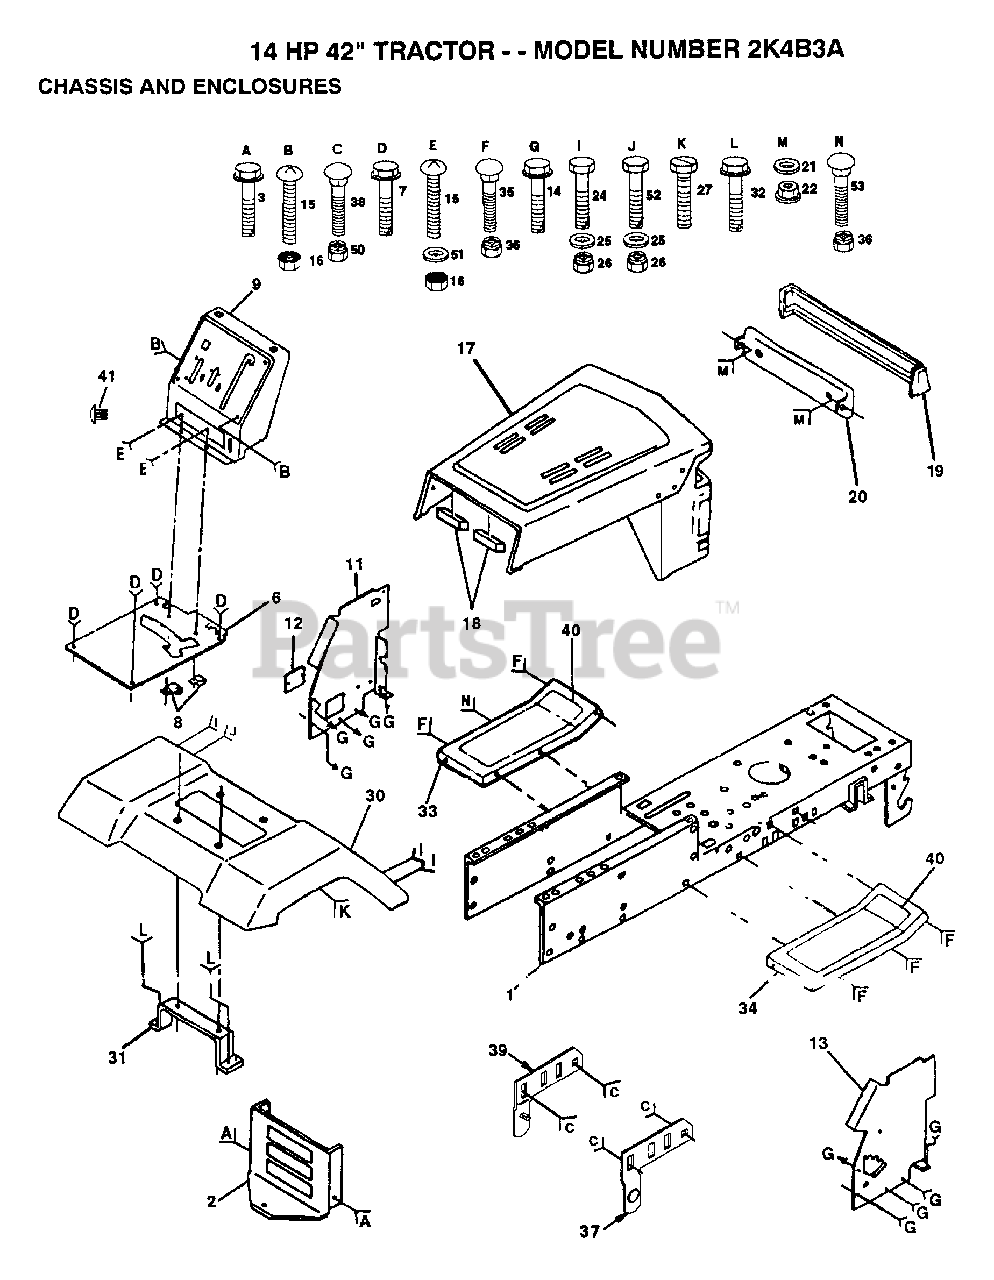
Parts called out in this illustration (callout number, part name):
3	SCREW
7	SCREW LT
8	CLIP T
11	PANEL DASH LH
12	COVER ACCESS
14	SCREW LT
15	SCREW
17	HOOD/GRILL ASM
21	WASHER PM
22	PAL NUT LT
25	WASHER
27	SCREW LT
30	FENDER
31	BRKT FENDER
32	SCREW
35	BOLT
37	PIVOT BRKT RH
38	BOLT
39	PIVOT BRKT LH
40	"PAD,FOOTREST"
41	PLUG BUTTON T
50	NUT
51	WASHER
